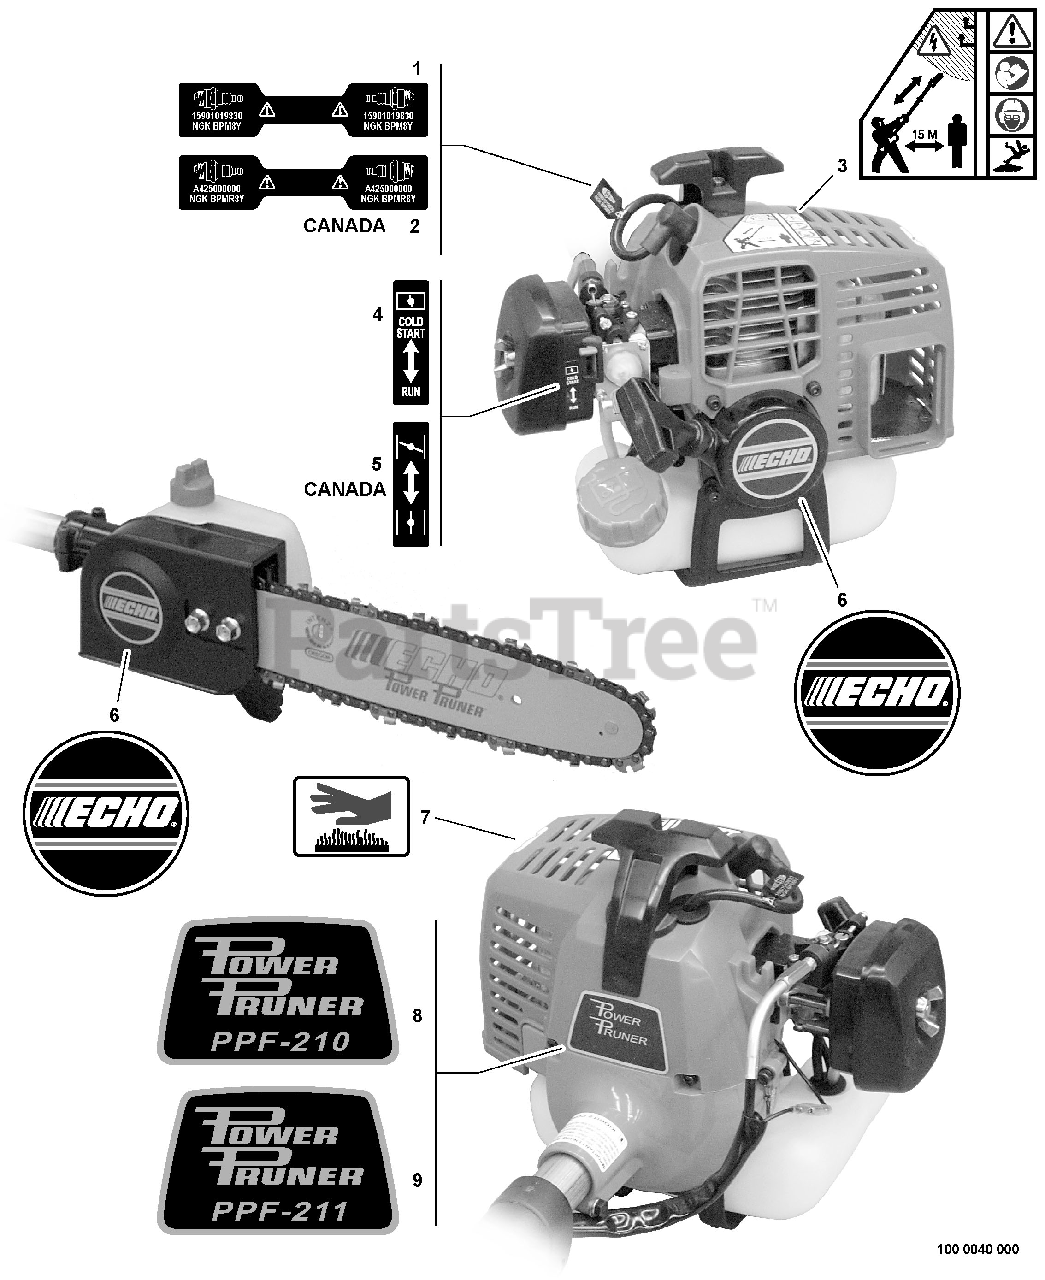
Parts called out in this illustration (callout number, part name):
1	LABEL - SPARK PLUG -- BPM-8Y
2	LABEL - SPARK PLUG -- BPMR-8Y
3	LABEL - CAUTION
4	LABEL - CHOKE
5	LABEL - CHOKE
6	LABEL - ECHO
7	LABEL - HOT SURFACE
8	LABEL - MODEL PPF-210
9	LABEL - MODEL PPF-211
